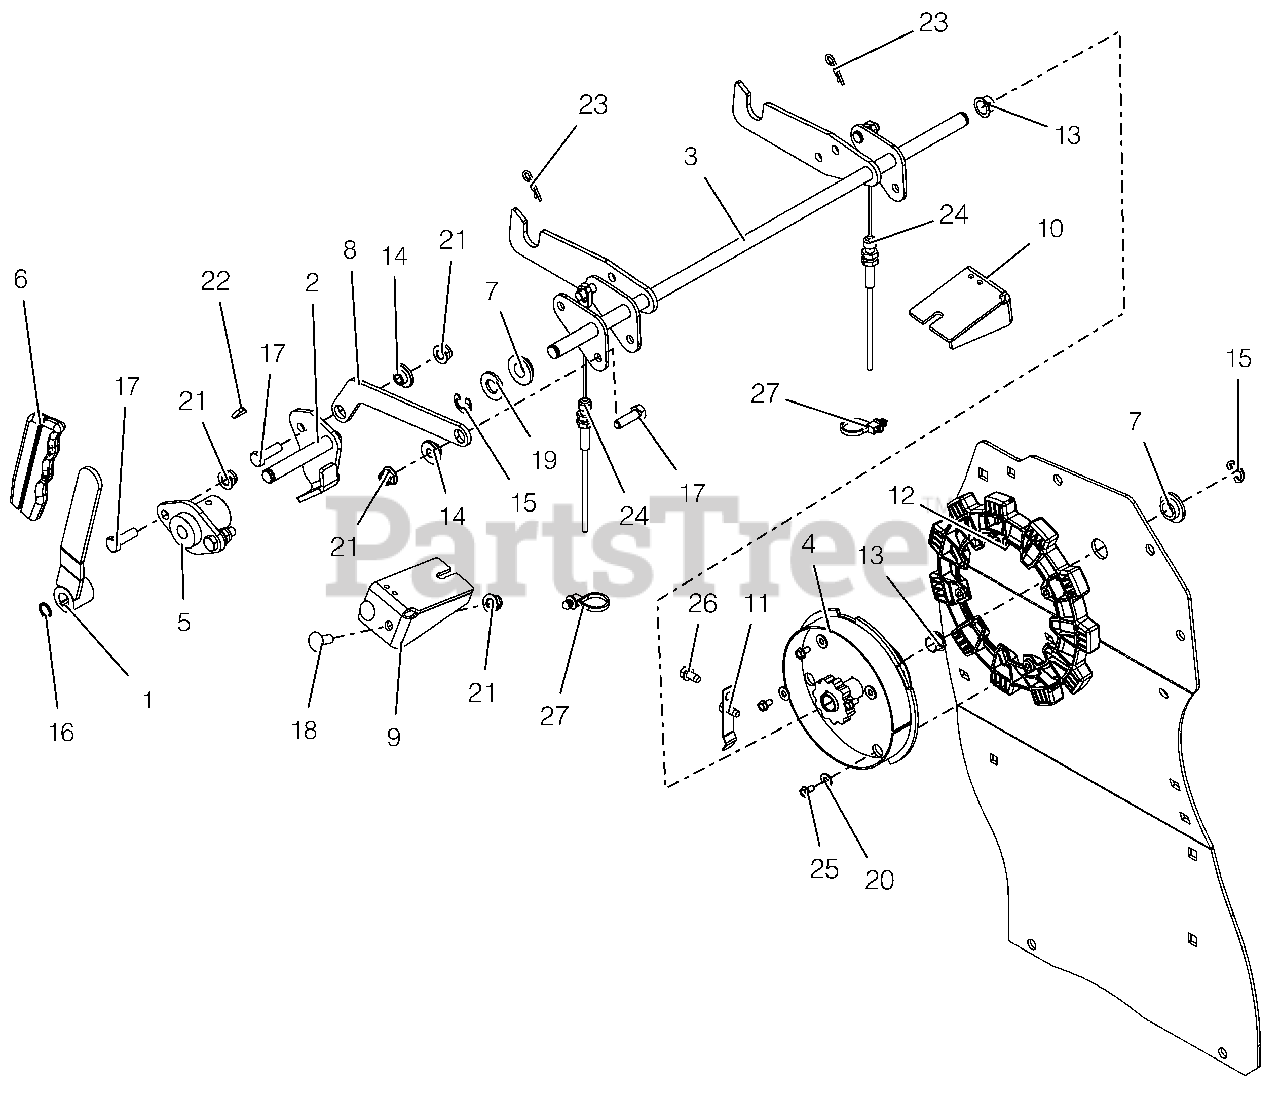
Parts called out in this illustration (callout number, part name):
1	WMT, PARKING BRAKE HANDLE
2	WMT, PARKING BRAKE ACTUATING
3	WLDMT, PS BRAKE INTERLOCK
4	KIT, 36" HOC WLDMT W/DECAL
5	BUSHING, FLANGED
6	GRIP, PARKING BRAKE (YELLOW)
7	BSHG-FLG .515X.750X.310X1.120
8	LINK, BRAKE INTERLOCK
9	BRKT, BRAKE CABLE MTG
10	BRKT, LH CABLE MTG
11	ARM, HOC DETENT
12	WHEEL, HOC
13	BUSHING, POLYLINER-.50 SPLIT
14	BSHG-FLG .32X.500X.344X.880
15	RG-RTNG-EXT .500X.042 (E)
16	RG-RTNG-EXT .500X.050 (SNAP)
17	@BLT-HEX .31-18X1.00 GR5 YWZC
18	@BLT-RDHDSQNK .31-18X.75 G5YZ
19	@WSHR-FL-STL.531X1.06X.095YWZC
20	@WSHR-FL-STL.219X.50X.049 YWZC
21	@NUT-LK-NYL-FLG .31-18 YWZC
22	KEY-WDRF .13X.63 HRD#5
23	PIN-HAIR INT .08X.18X1.18 YWZC
24	CABLE, PROSTANCE P.BRAKE
25	SCR-TAP 10-24X.375 PRE-COAT 80
26	SCR-TAP .25-20X.50 HWH TR YWZ
27	CABLE TIE W/ TREE (.25 HOLE)
